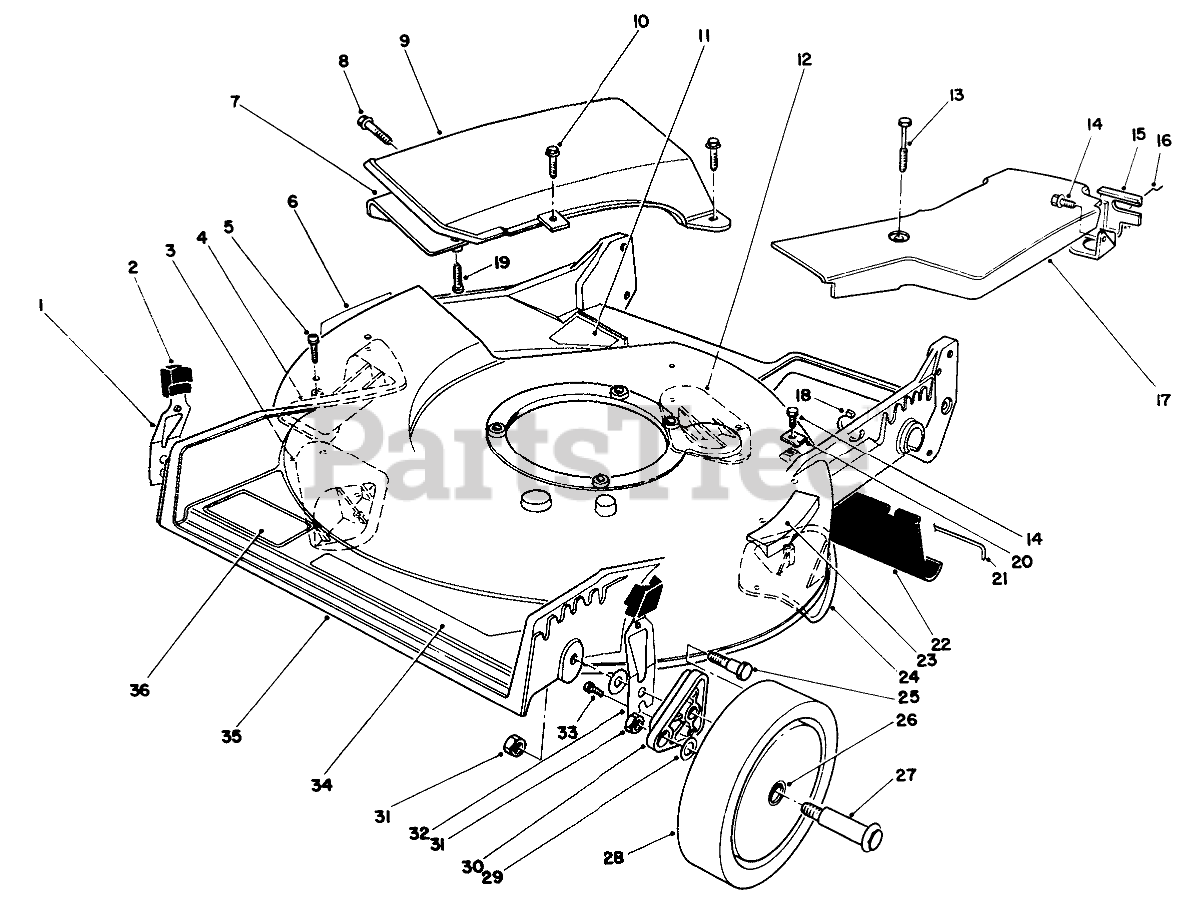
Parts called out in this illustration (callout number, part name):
1	RH SPRING ARM ASSEMBLY
2	KNOB-ARM
3	KICKER
4	KICKER
5	#8 X .625" PHILPS PAN H
6	DECAL-DANGER
7	Deflector-Recycler
8	SCREW AND WASHER ASM
9	Cover Assembly (Incl. Ref. #7 & 19)
10	SCREW-HWH
11	DECAL - DANGER
12	KICKER
13	SCREW-HHFTF
14	SCREW-HWHTF
15	Bracket-Adj. Trac
16	RETAINER-CABLE
17	BELT COVER
18	TIE-CABLE
19	Screw-Pan Hd.
20	CLAMP-CABLE
21	ROD-SHIELD
22	SHIELD-TRAILING
23	STEP PAD DECAL
24	KICKER
25	SCREW-SHOULDER
26	BUSHING
27	WHEEL BOLT
28	Wheel & Tire Assembly (Incl. Ref. #26)
29	WASHER
30	ARM-PIVOT, FRONT
31	Nut
32	LH SPRING ARM ASSEMBLY
33	SCREW-HWH
34	DECAL - DECK
35	Housing (Incl. Ref. #3-6, 12, & 24)
36	DECAL
